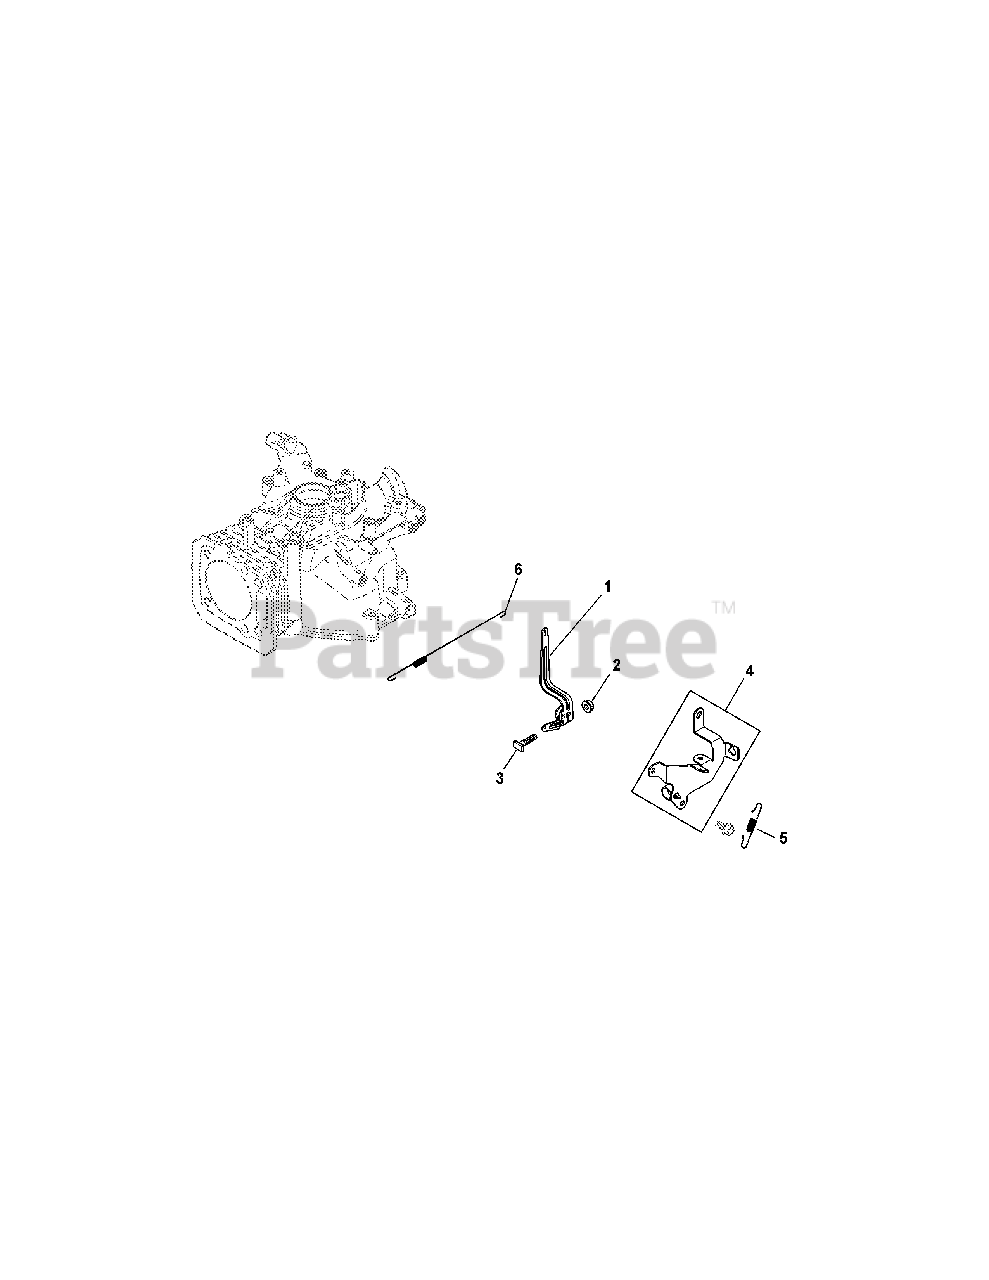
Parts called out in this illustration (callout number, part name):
1	Governor Lever
2	Nut, Hex Flange, M6
3	Screw, Rectangle Head, M6
4	Control Bracket
5	Governor Spring
6	Linkage Spring
